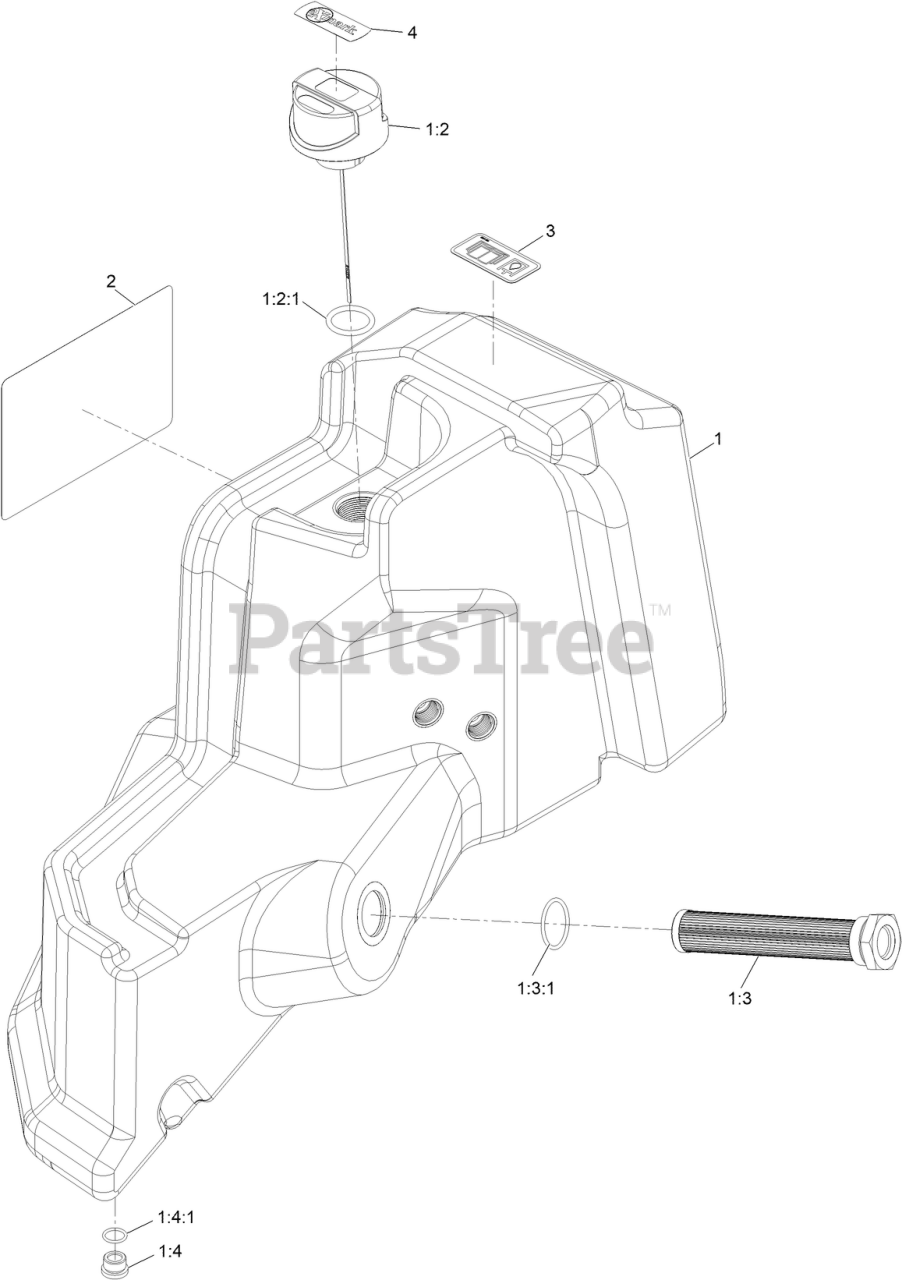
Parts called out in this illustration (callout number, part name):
1	Hydraulic Tank ASM
1:2	CAP-HYDRAULIC, VENTED BREATHER
1:3	STRAINER-TRANSAXLE
1:4	PLUG ASM W/MAGNET
1:4:1	O-RING
2	DECAL-Z-AERATE-50-INCH
3	DECAL-HYD FLUID
4	DECAL-EXMARK LOGO
